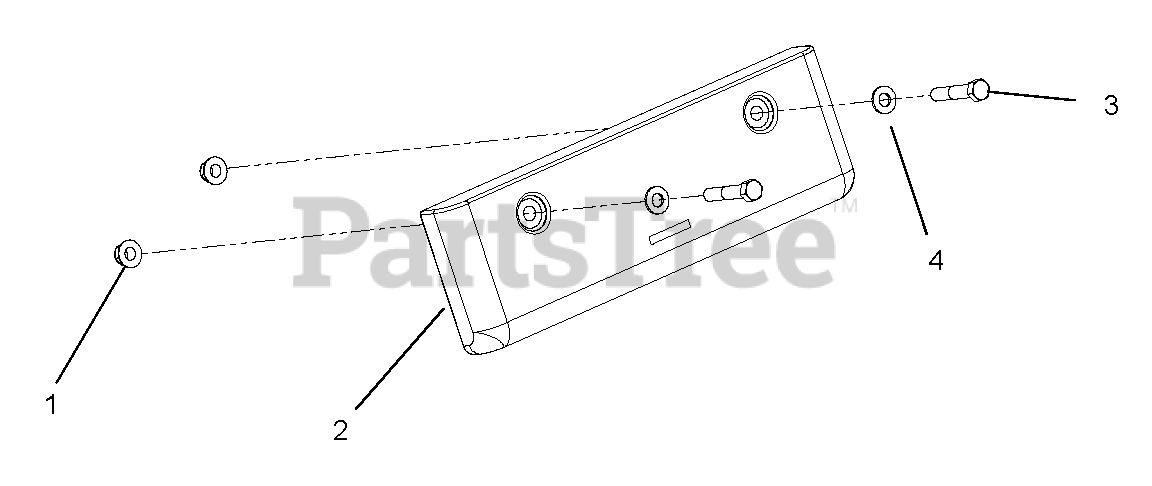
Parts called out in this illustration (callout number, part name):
1	Nut, Nyloc Flange .50-13
2	Weight, Cast Iron
3	Bolt, Hex .50-13 x 2.75
4	Washer, Flat Steel 531 x 1.06 x .095
